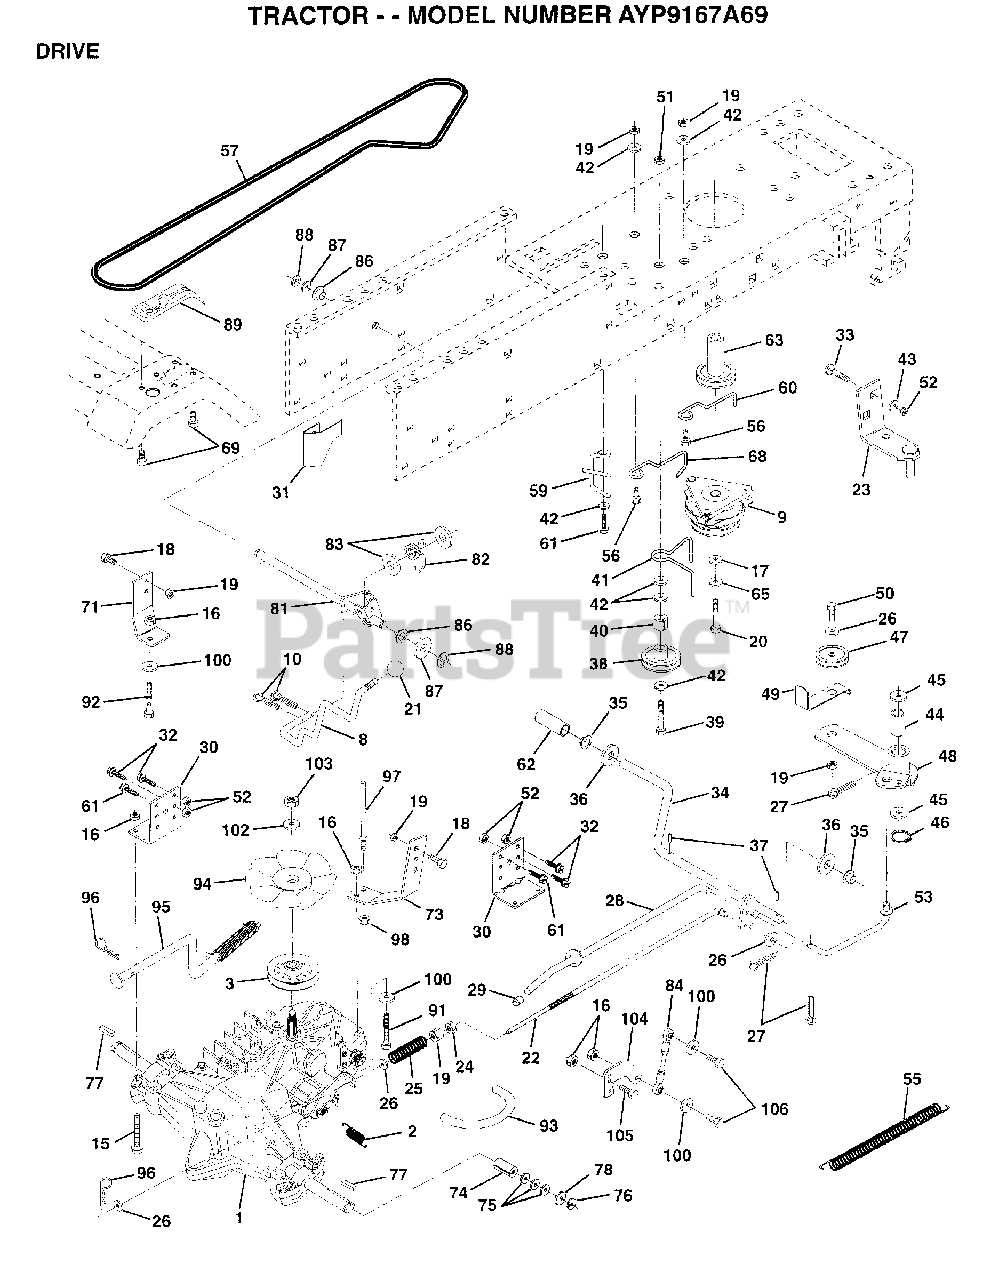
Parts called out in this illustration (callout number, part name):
1	TRANSAXLE.3100650
2	SPRING RET BRAKE
3	PULLEY.TRANSAXLE
8	ROD SHIFT FEND YT
10	PIN COTTER 1/8
15	BOLT.HX.FLG.5/16
16	NUT
17	WASHER
18	BOLT
19	NUT
20	BOLT.7/16-20X4.25
21	KNOB T (1/2-HOLE)
22	ROD.BRAKE.HYDRO.
23	BRACKET.ASM.MTG
24	NUT
25	SPRING ROD LT
26	WASHER
27	COTTER PIN
28	ROD.BRAKE.PARK.LT
30	TRANSAXLE MTG BKT
31	"KEEPER,BELT LH T"
32	BOLT
33	BOLT
34	SHAFT.PEDAL.FOOT
35	NYLON BEARING
36	WASHER LT
38	PULLEY.IDLER.FLAT
39	BOLT
40	SPACER T
41	BELT KEEPER LT
42	WASHER
43	WASHER T
44	"LY, BEARING"
45	WASHER LT
46	KLIP RING
48	ARM IDLER
49	RETAIN BELT
53	"LINK, CLUTCH T"
55	"SPRING, RETURN LT"
57	"BELT.GD DRV 82"""
59	KEEPER BELT CNTSP
60	"KEEPER,BLT ENG LT"
61	SCREW
62	PEDAL COVER T
63	PULLEY CLU ELEC
65	LOCKWASHER
68	KEEPER BELT ENGLH
69	SCREW HEXWSH H-L
71	STRAP TORQ LH HYD
73	STRAP TORQ RH HYD
74	SPACER SPLIT
75	WASHER
76	E-RING LT
77	SQUARE KEY
78	WASHER
82	"SPRING,TORSION"
83	WASHER
84	ROD.TIE.BALL.4.75
86	BUSHING
87	WASHER D
88	KLIP RING
92	HEX BOLT
93	"LINE FUEL HYD 4"""
94	"FAN 7"" HYDRO"
96	RETAINER M
97	BOLT KEEPER RH
98	NUT
102	WASHER BELLEVILLE
104	ARM CONTROL HYDRO
105	SCREW CAP 5/16-18
106	BOLT
